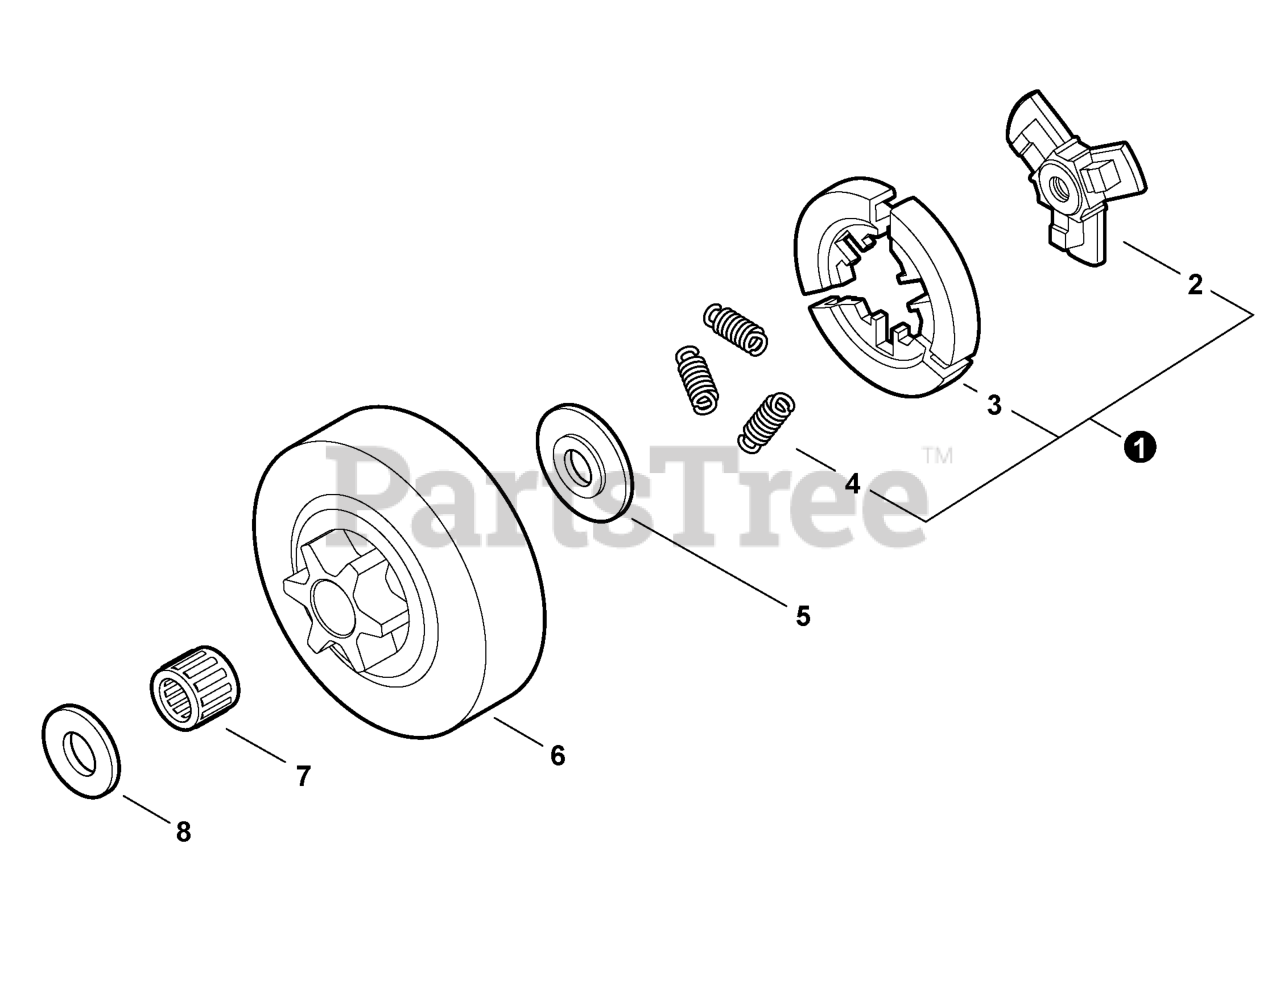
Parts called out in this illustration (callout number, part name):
1	CLUTCH ASSY
2	HUB, CLUTCH
3	CLUTCH SHOE SET (3PCS)
4	SPRING, CLUTCH
5	PLATE, CLUTCH
6	DRUM, CLUTCH 3/8"
7	BEARING, NEEDLE 10
8	WASHER 10
